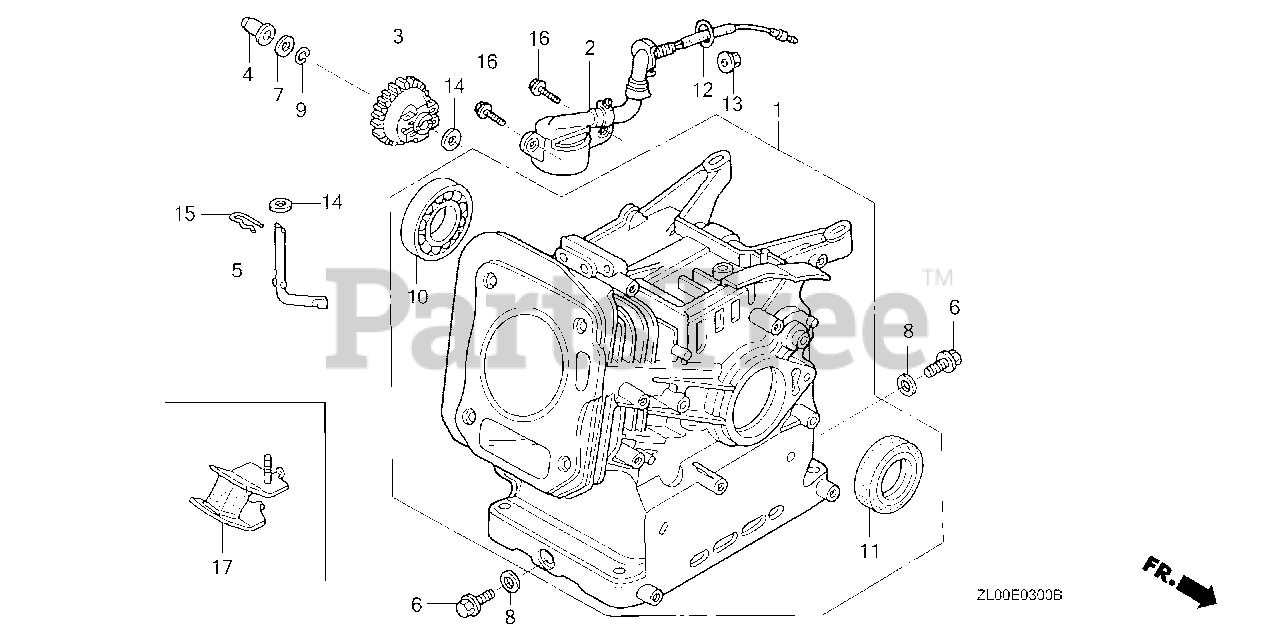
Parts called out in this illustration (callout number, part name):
1	CYLINDER ASSY.
2	SWITCH ASSY., OIL LEVEL
3	GOVERNOR ASSY.
4	SLIDER, GOVERNOR
5	SHAFT, GOVERNOR ARM
6	BOLT, DRAIN PLUG
7	WASHER, THRUST (6MM)
8	WASHER, DRAIN PLUG (10.2MM)
9	CLIP, GOVERNOR HOLDER
10	BEARING, RADIAL BALL (6205TMB) (NTN)
11	OIL SEAL (25X41X6)
12	O-RING (14MM) (ARAI)
12	O-RING (14MM) (NOK)
13	NUT, FLANGE (10MM)
14	WASHER, PLAIN (6MM)
15	PIN, LOCK (8MM)
16	BOLT, FLANGE (6X12)
